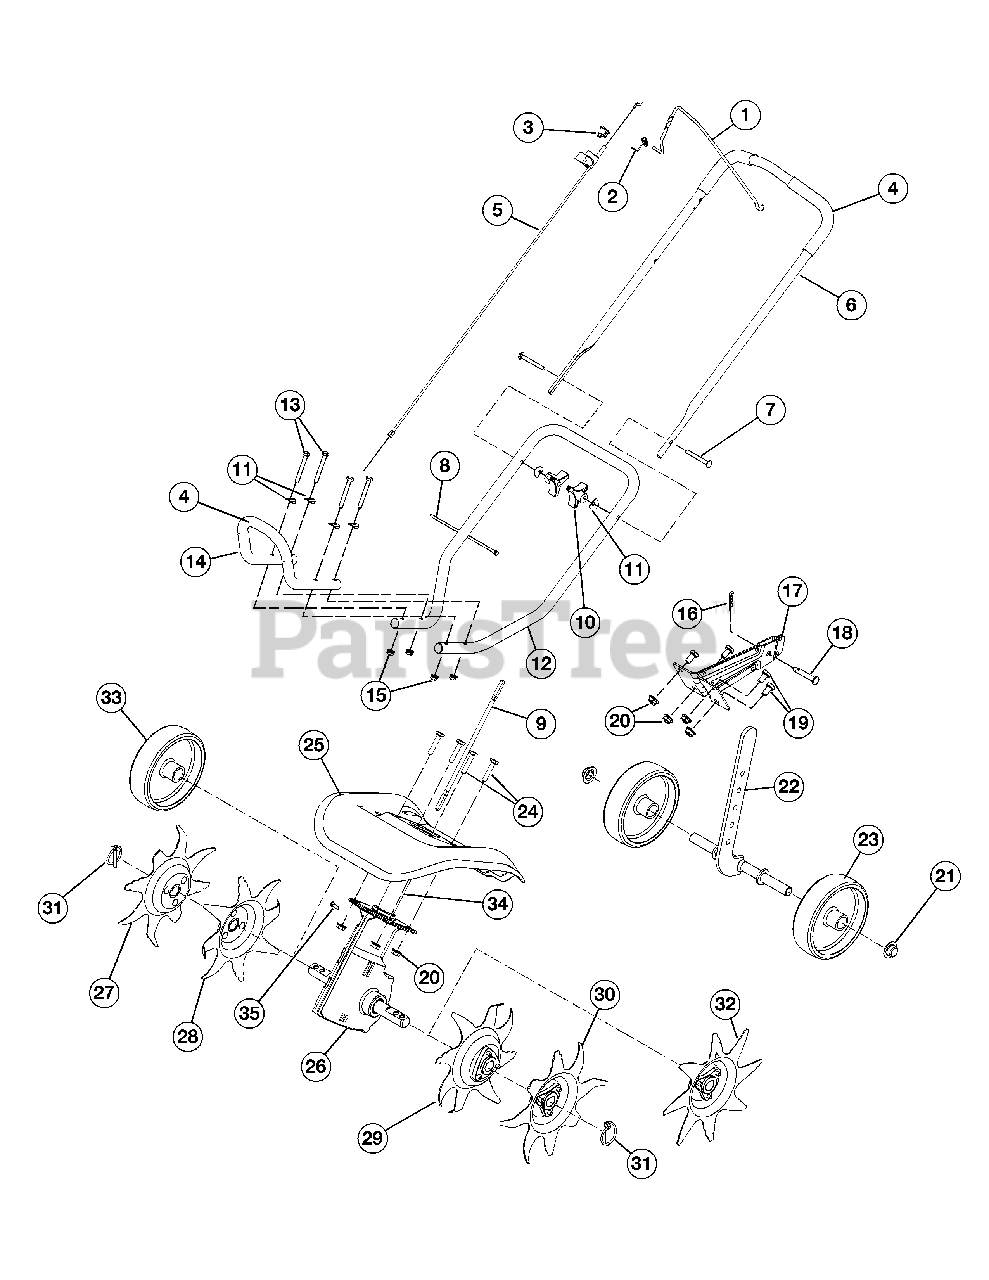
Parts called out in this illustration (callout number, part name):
1	Throttle Control
2	Torsion Spring
3	On/Off Switch
4	Foam Grip
5	Throttle Cable
6	Upper Handle
8	Cable Tie
9	Flex Shaft
11	Shoulder Washer
14	Front Handle
16	Cotter Pin
17	Tailpiece Bracket Assembly
18	Clevis Pin
19	Cap Screw
22	Wheel Support Bracket Assembly
23	Wheel
24	Cap Screw
25	Tine Shield
26	Gear Box Assembly
27	Outer Tine (Right Side)
28	Inner Tine (Right Side)
29	Inner Tine (Left Side)
30	Outer Tine (Left Side)
32	Edger Tine
33	Edger Wheel
34	Drive Shaft Housing
35	Sleeve Retaining Bolt
